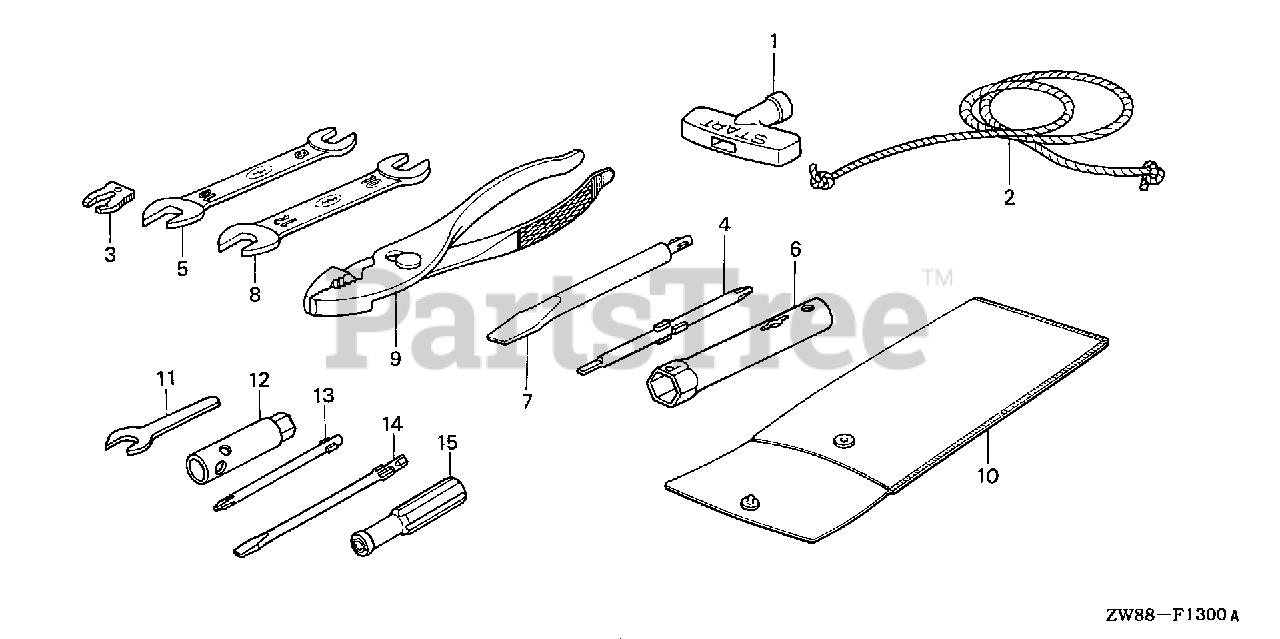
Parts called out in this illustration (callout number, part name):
1	GRIP, STARTER
1	KNOB, RECOIL SRARTER
2	ROPE, RECOIL STARTER (1300MM)
3	CLIP, EMERGENCY LOCK
4	DRIVER
5	SPANNER (8X10)
6	WRENCH, SPARK PLUG
7	SCREWDRIVER, CHECK BOLT
8	SPANNER (10X12)
9	PLIERS (135) (KOWA)
9	PLIERS (135)
10	BAG, TOOL (160MM)
11	SPANNER (8MM) (NOT AVAILABLE)
12	WRENCH, BOX (10MM)
13	DRIVER 1, PLUS SCREW (NO.2)
14	DRIVER 3, MINUS SCREW (NO.2)
15	GRIP, SCREW DRIVER
